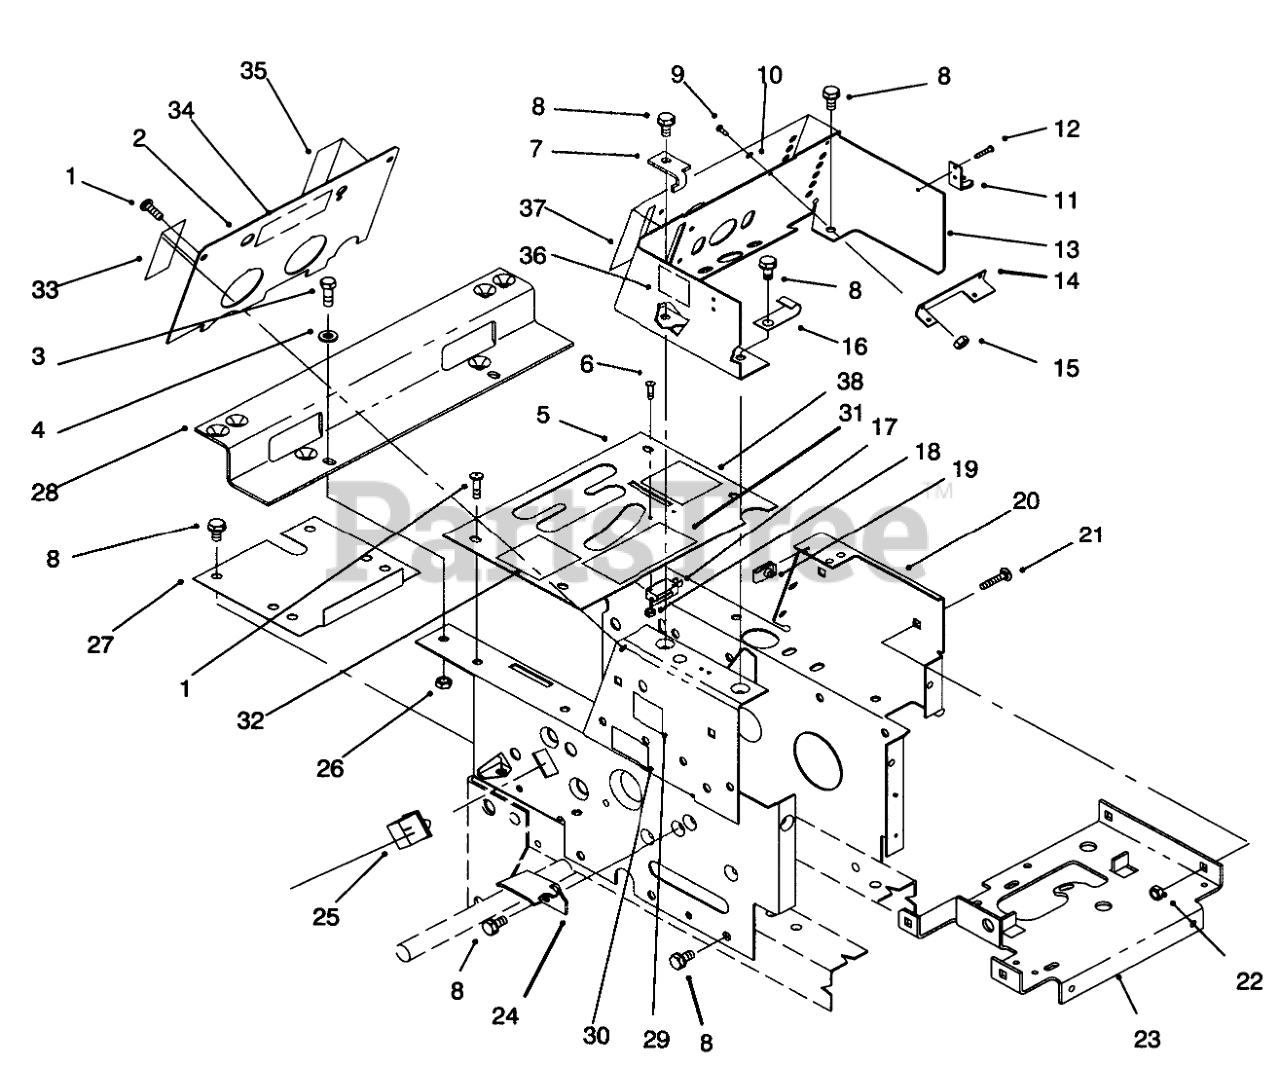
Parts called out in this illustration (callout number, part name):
1	SCREW-PPH
2	Plate-Hoodstand
3	SCREW-HH
4	WASHER-PLAIN
5	Plate-Shift Cover
7	STOP-PTO
8	Bolt
11	KEEPER-LATCH
12	POPRIVET 1/8X 1/8 BK
13	CONSOLE B
16	J-CLIP
20	Hoodstand
21	BOLT CARR. 5/16X1/2 BK
22	Nut
23	SUPORT-BATERYB
24	Bracket-Belt
25	SWITCH INTERLOCK
26	NUT-LOCK, NI
27	Cover-Dust
28	BRACKET-FENDER B
30	DECAL - MODEL 312-8
31	DECAL-DANGER
32	DECAL-SHIFT PATTERN
33	DECAL PTO CLUTCH
34	DECAL-BACK PLATE
34	Decal-Back Plate
35	DECAL-LIFT
36	DECAL ELECT SYSTEM
37	DECAL-CONSOLE
38	DECAL-PARKING, BRAKE
